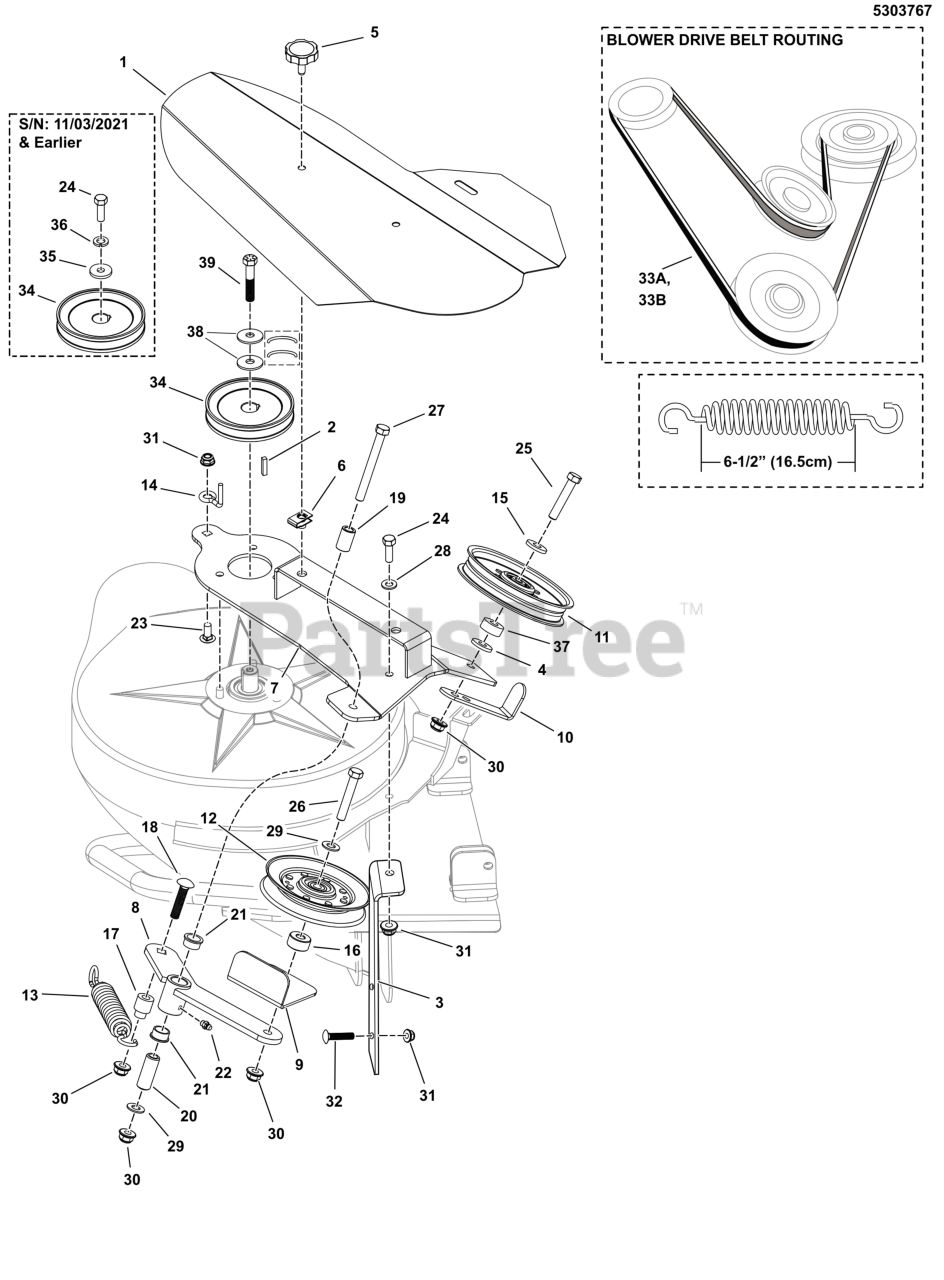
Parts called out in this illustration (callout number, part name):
1	HOOD W/ DECALS - TURBO PRO-MAX
2	KEY, 3/16" SQ. X 3/4
3	BRACKET, FRONT SUPPORT, 61" COM - BLK
3	BRACKET, PLATE SUPPORT, TMAX-BLK
4	WASHER, 3/8" Fender
5	KNOB, 5/16-18 X 1.00, ROSETTE BLACK
6	BODY CLIP, 5/16-18-7GA MATERIAL
7	ASSEMBLY, PULLEY PLATE, T-MAX (52,60,61)
8	ASSEMBLY, IDLER ARM - TURBO-VAC
9	RETAINER, BELT, WIDE - BLK
10	RETAINER, BELT
11	PULLEY-IDLER 04.00 OD 0.378ID 1.06 W BRG
12	PULLEY-IDLER-V, 4.85OB, .38ID
13	SPRING-EXT, 1.04 ODX6.935LGX.148WR, BLK
14	BELT KEEP, .19 X 1.25 - BK
15	WSHR,.406X1.0X.134,FLT,TYPE A,ZINC/CLEAR
16	SPACER, .39 X 1.00 X .50, PM, CZ
17	SPACER,3/8X3/4X15/16
18	BOLT,3/8-16X1.750,SHORT NECK CRRG,ZC/CL
19	SPACER, .39 X .63 X 1.00, YZ
20	SPACER, .38 X .625 X 1.62, YZ
21	BUSHING-0.628IDX0.751ODX0.400LG PWDR MTL
22	GREASE FITTING, 1/4-28 Straight
23	BOLT, 5/16-18 X 3/4, CARRIAGE, GD5, CZ
24	BOLT, 5/16-18 X 1" GRD5 YZ
25	BOLT, 3/8-16 X 1-3/4" GD5 CZ
26	BOLT, 3/8-16 X 2-1/4" GD5 CZ
27	BOLT, 3/8-16 X 3-1/2" GD5 CZ
28	WASHER, 5/16" SAE
29	WASHER, 3/8 SAE
30	NUT, 3/8 - 16 HEX NYLOCK FLANGE
31	NUT, 5/16-18 HEX NYLOCK FLANGE NUT
32	BOLT, 5/16-18 X 1, CARRIAGE, GD5, CZ
33A	BELT, A SEC, 81.1"EL, ARAMID, WRPD
33B	BELT
34	PULLEY, COMMERCIAL PRO
35	WASHER-0.312(0.34IDX1.00ODX.13THK)BLK
36	WASHER, 5/16 LOCK CZ
37	SPACER-0.390ID 0.90 OD 0.34 LG P'MTL YEL
38	BELLEVILLE WASHER, 1.187X.39X.089, SS
39	BOLT, 3/8-16 X 2.0, GD8, PHOS
